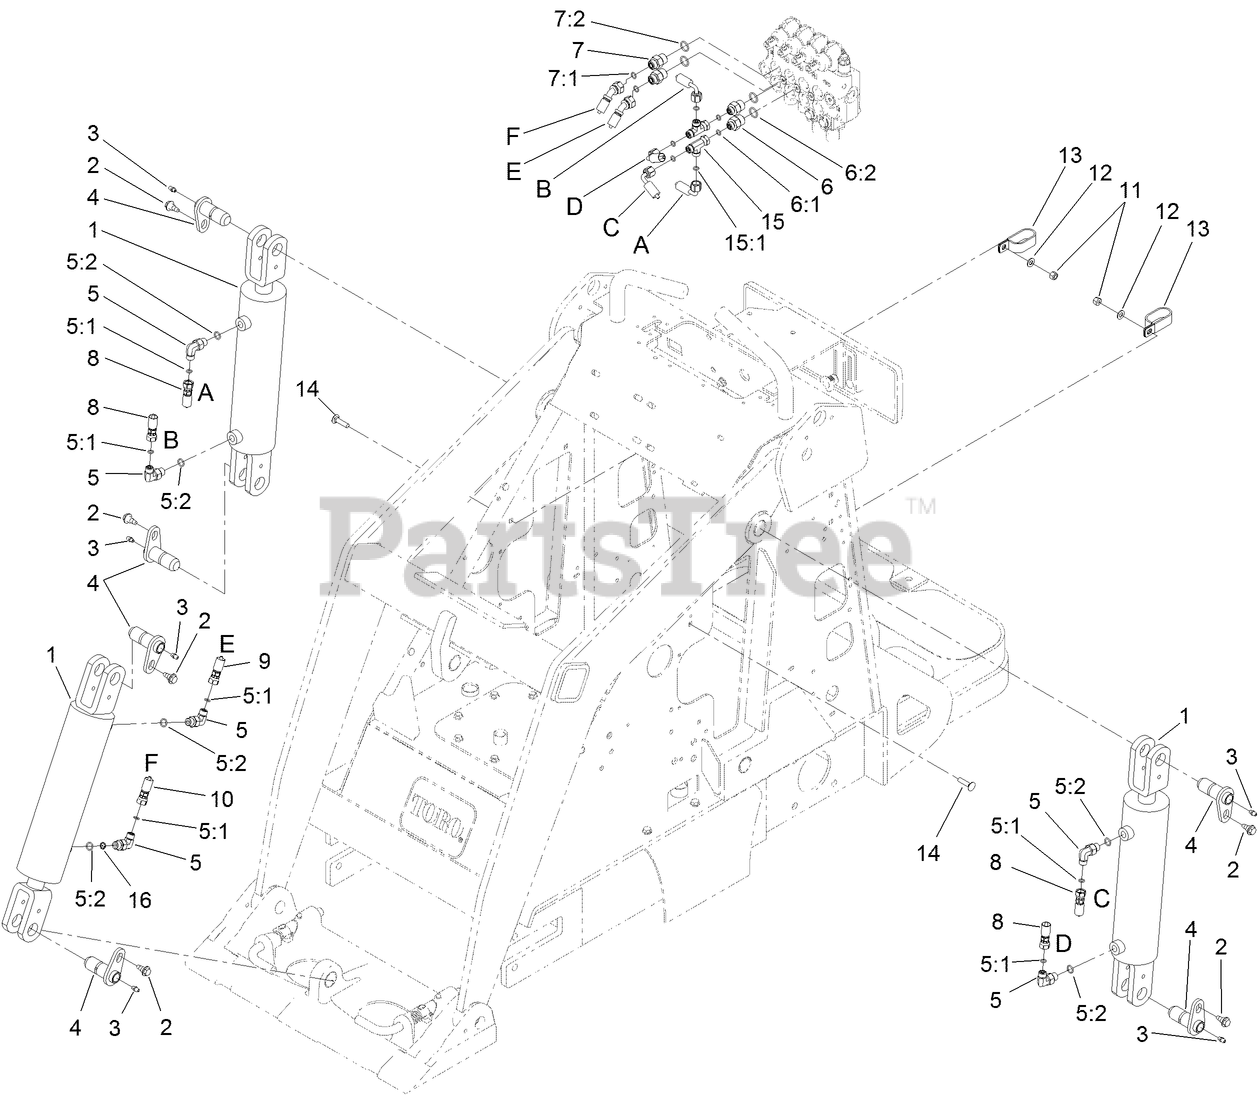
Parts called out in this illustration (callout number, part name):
1	CYLINDER-HYD
2	BOLT-SHOULDER
3	FITTING-GREASE
4	PIN-PIVOT
5	FITTING-ELBOW 90
5:1	O-RING
5:2	O-RING
6	FITTING-STR
6:1	O-RING
6:2	O-RING
7	FITTING-STRAIGHT
7:1	O-RING
7:2	O-RING
8	HOSE-HYD
9	HOSE-HYD
10	HOSE-HYD
11	NUT-LOCK, NI
12	WASHER-PLAIN
13	CLAMP-R, DOUBLE
14	SCREW-CARR
15	FITTING-HYD
15:1	O-Ring
16	ORIFICE-PORT INSERT, ONE WAY
